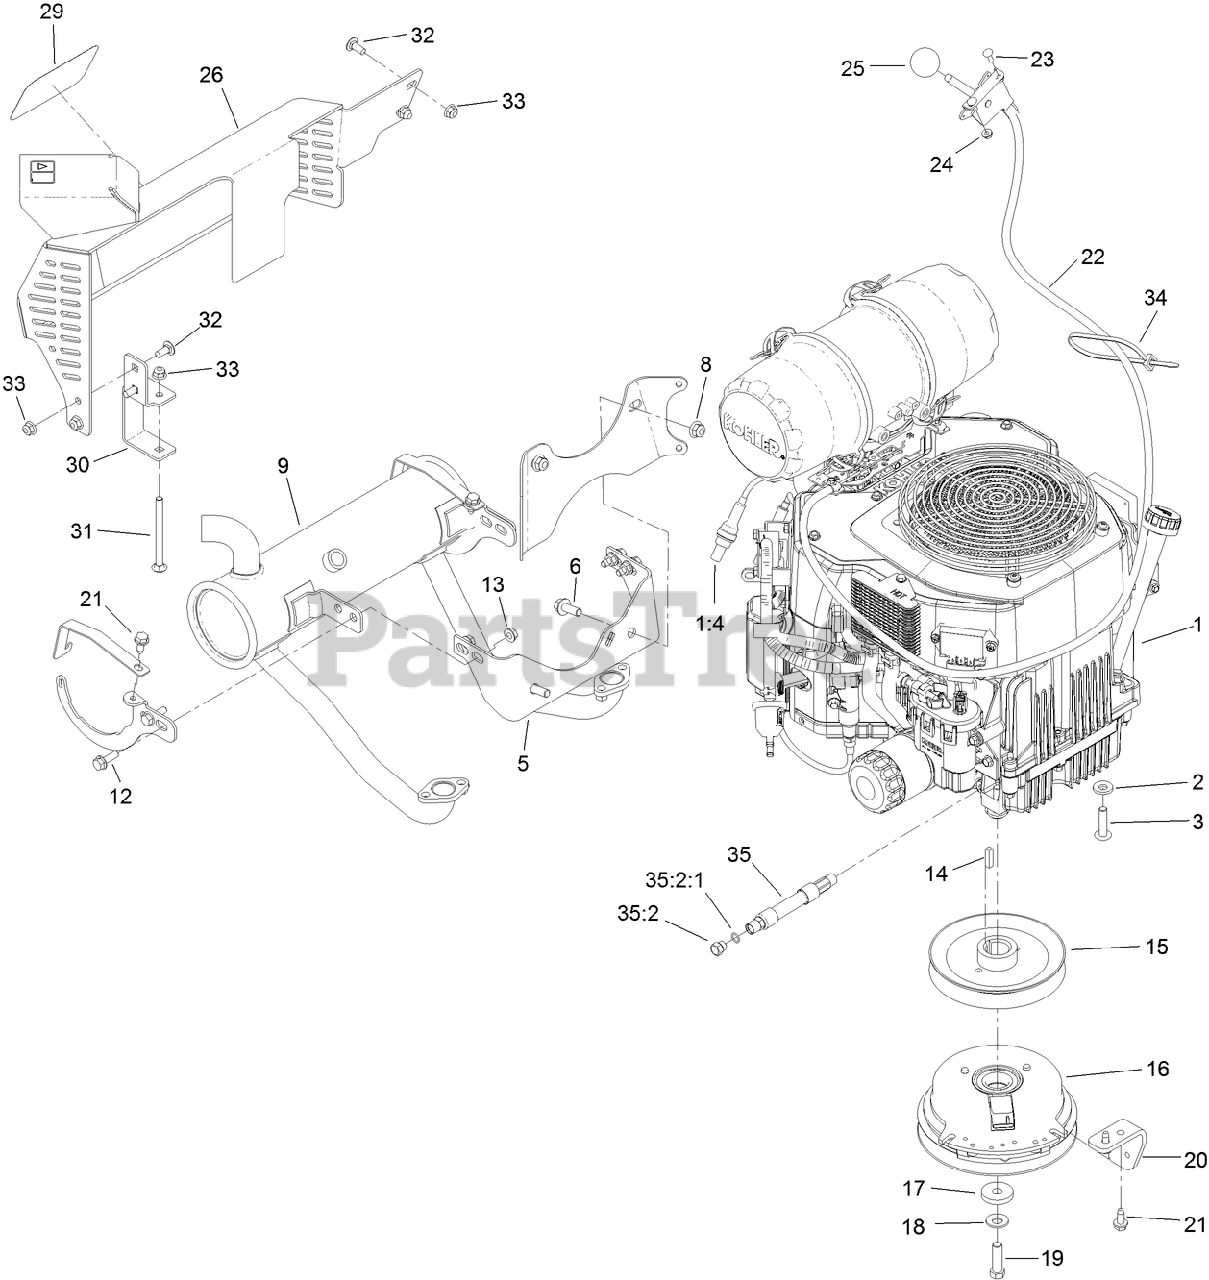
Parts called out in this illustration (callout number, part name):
1	ENGINE-KOHLER, ECV749
1:4	SENSOR-OXYGEN
2	WASHER-BELLEVILLE
3	SCREW-BHTF
5	BRACKET-MUFFLER
6	SCREW-HHF
8	NUT-HF, NI
9	MUFFLER-KOHLER
12	SCREW-HHF
13	NUT-HF
15	PULLEY
16	CLUTCH-200CMS
17	WASHER
18	WASHER-SPRING
19	SCREW-HH
20	STOP-CLUTCH
21	SCREW-HWHTF
22	THROTTLE ASM
23	BOLT-CARR
24	NUT-LOCK, FLANGE
25	KNOB-BALL
26	MUFFLER GUARD ASM
29	DECAL
30	BRACKET-MOUNTING, GUARD
31	SCREW-CARR
32	SCREW-CARR
33	NUT-HF, NI
34	TIE-CABLE
35	HOSE ASM
35:2	PLUG-HH
35:2:1	O-RING
